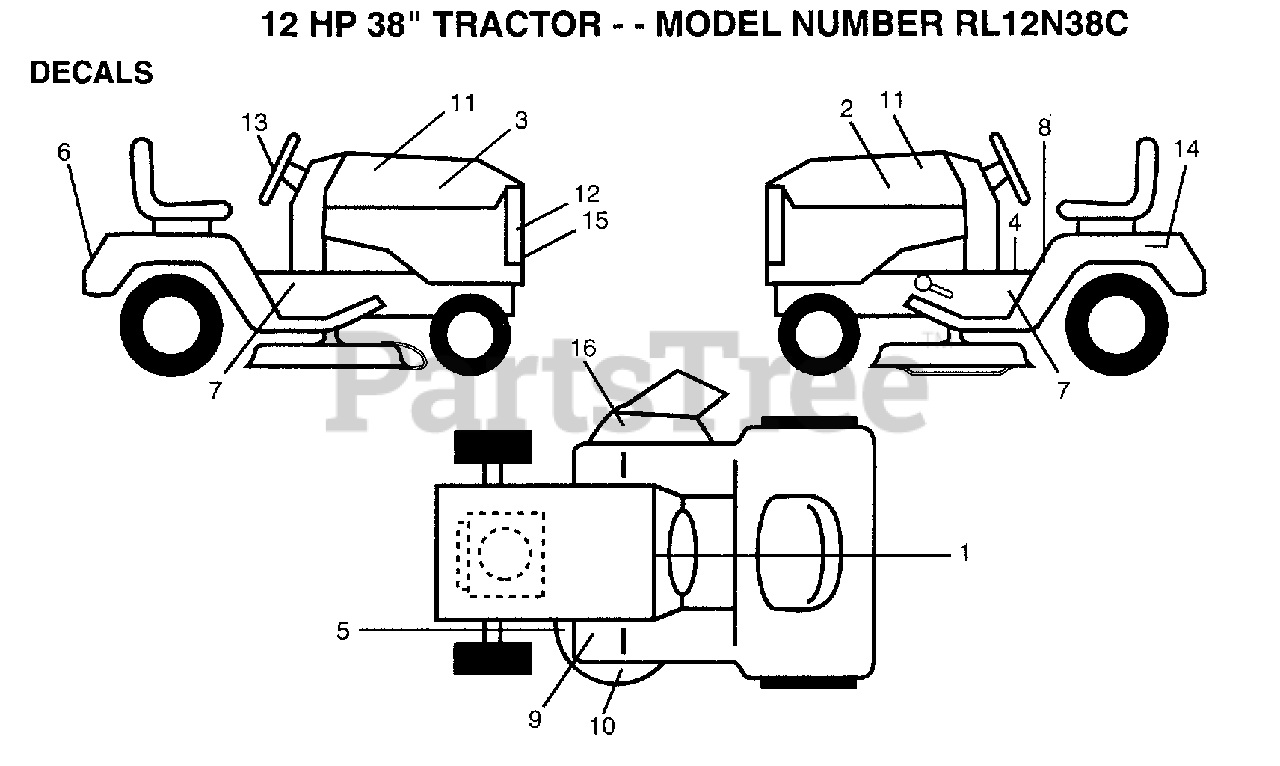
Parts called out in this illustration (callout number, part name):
1	DECAL.DASH.INSTR.
2	DECAL HOOD LH RLY
3	DECAL HOOD RH RLY
4	DECAL BRAK PARK
5	DECAL
6	FENDER DECAL
7	DECAL CHASSIS SPEED DECK
8	DECAL CAUTION
9	DECAL T
11	DECAL.HOOD.INS.
12	GRILL DECAL
13	"DECAL,STR WHL"
14	DECAL
16	"DECAL, WARNING"
